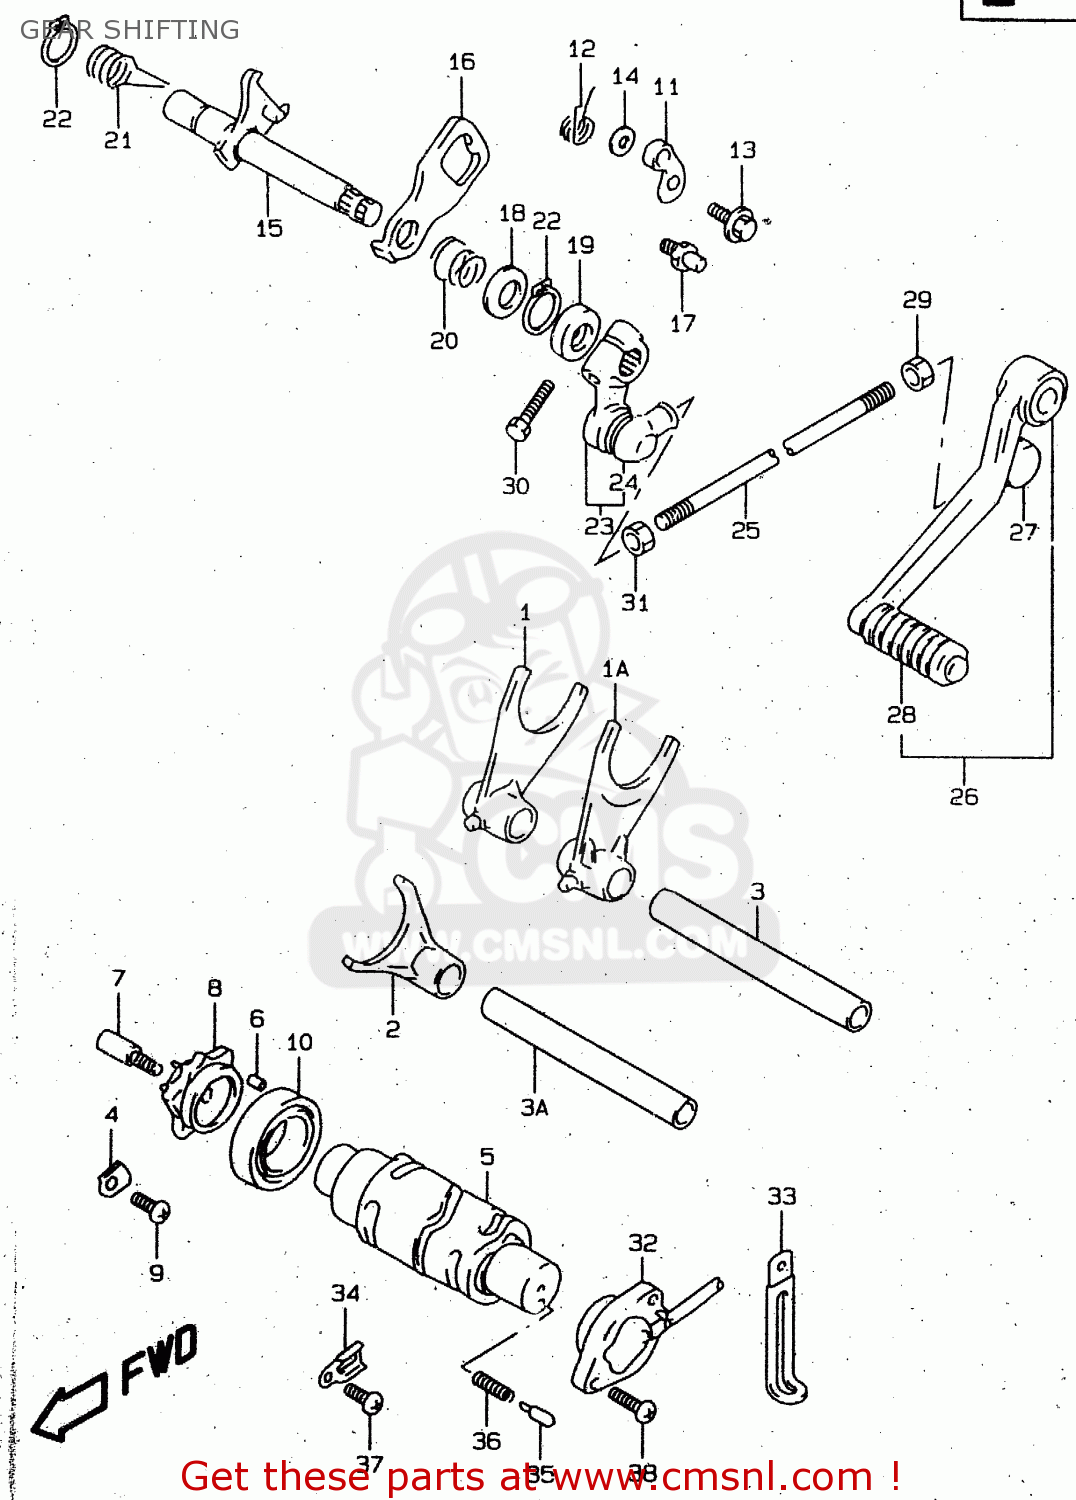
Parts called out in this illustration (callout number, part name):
1	FORK,GEAR SHIFT
1A	FORK,GEAR SHIFT NO.1
2	FORK,GEAR SHIFT NO.3
3	SHAFT,GEAR SHIFT FORK
3A	SHAFT,GEAR SHIFT FORK NO.2
4	RETAINER
5	CAM,GEAR SHIFT
6	PIN
7	PIN,SHIFT CAM DRIVEN GEAR
8	PLATE,GEAR SHIFT CAM
9	SCREW
10	BEARING
11	STOPPER,GEAR SHIFT CAM
12	SPRING,SHIFT CAM STOPPER
13	BOLT(6X14.3)
14	WASHER
15	SHAFT,GEAR SHIFT
16	PLATE,GEAR SHIFT CAM DRIVE
17	STOPPER,GEAR SHIFT CAM
18	SHIM(14X22X1)
19	SEAL,OIL(14X22X6)
20	SPRING
21	SPRING
22	CIRCLIP
23	ARM,GEAR SHIFT LINK
24	COVER,DUST
25	ROD,GEAR SHIFT LINK
26	LEVER ASSY,GEAR SHIFT
27	COVER,DUST
28	RUBBER,GEAR SHIFT PEDAL
29	NUT
30	BOLT
31	NUT
32	BASE ASSY,GEAR SHIFT TERMINAL
33	CLAMP(L:45)
34	CLAMP,GENERATOR LEAD WIRE
35	PIN(5X15.5)
36	SPRING
37	SCREW
38	SCREW
